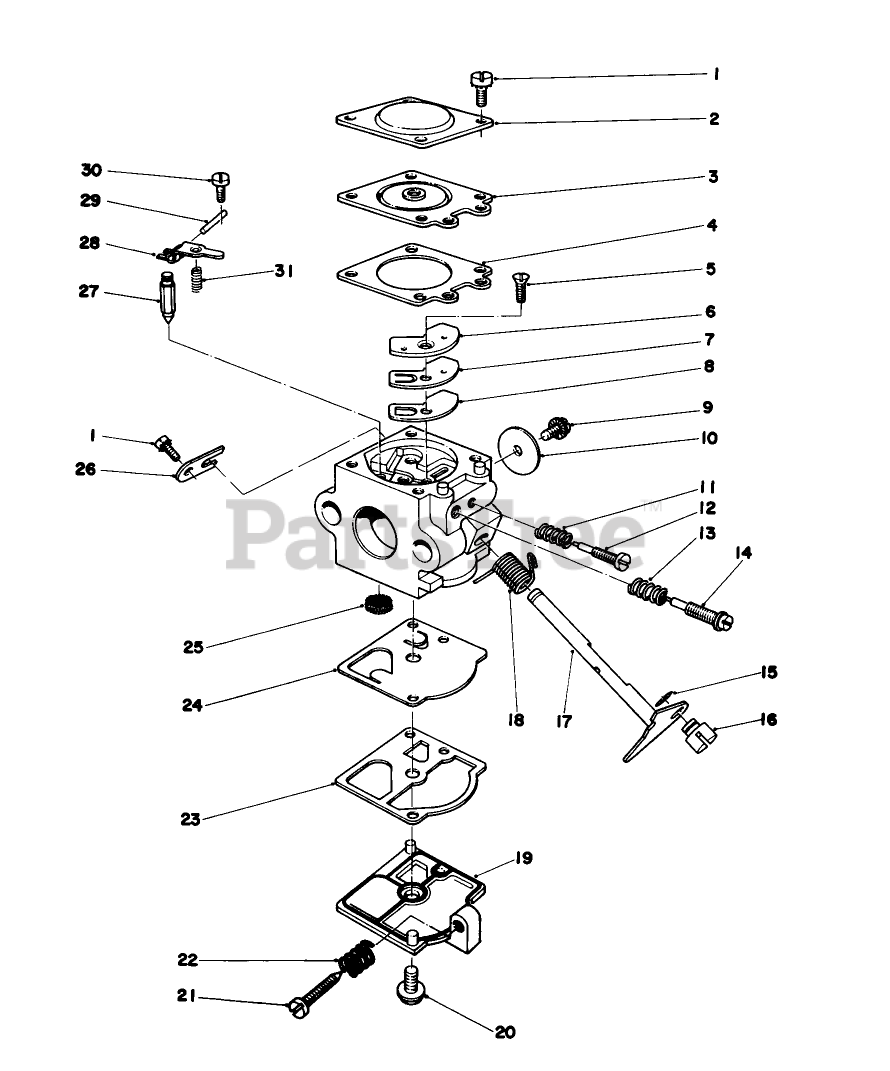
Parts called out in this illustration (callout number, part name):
1	Screw
2	Cover, Diaphragm
3	METERING DIAPHRAGM
4	Gasket, Diaphragm
5	Screw-Circuit Plate
6	Plate, Circuit
7	Diaphragm Circuit Plate
8	Gasket-Circuit Plate
9	Screw
10	Valve Throttle
11	Spring, Needle
12	Idle Needle
14	Needle, High Speed
16	Swivel
17	Shaft Ass-y. Throttle
18	Spring-Throttle Lever
19	Cover, Fuel Pump
20	Screw
21	Screw, Idle Adjust
22	Spring, Idle Screw
23	PUMP GASKET
24	Diaphragm Fuel Pump
25	Screen Inlet
26	Clip Throttle Shaft
27	INLET NEEDLE VALVE
28	Lever Metering
29	Metering Lever Pin
30	Screw-Metering Pin
31	Spring, Lever
